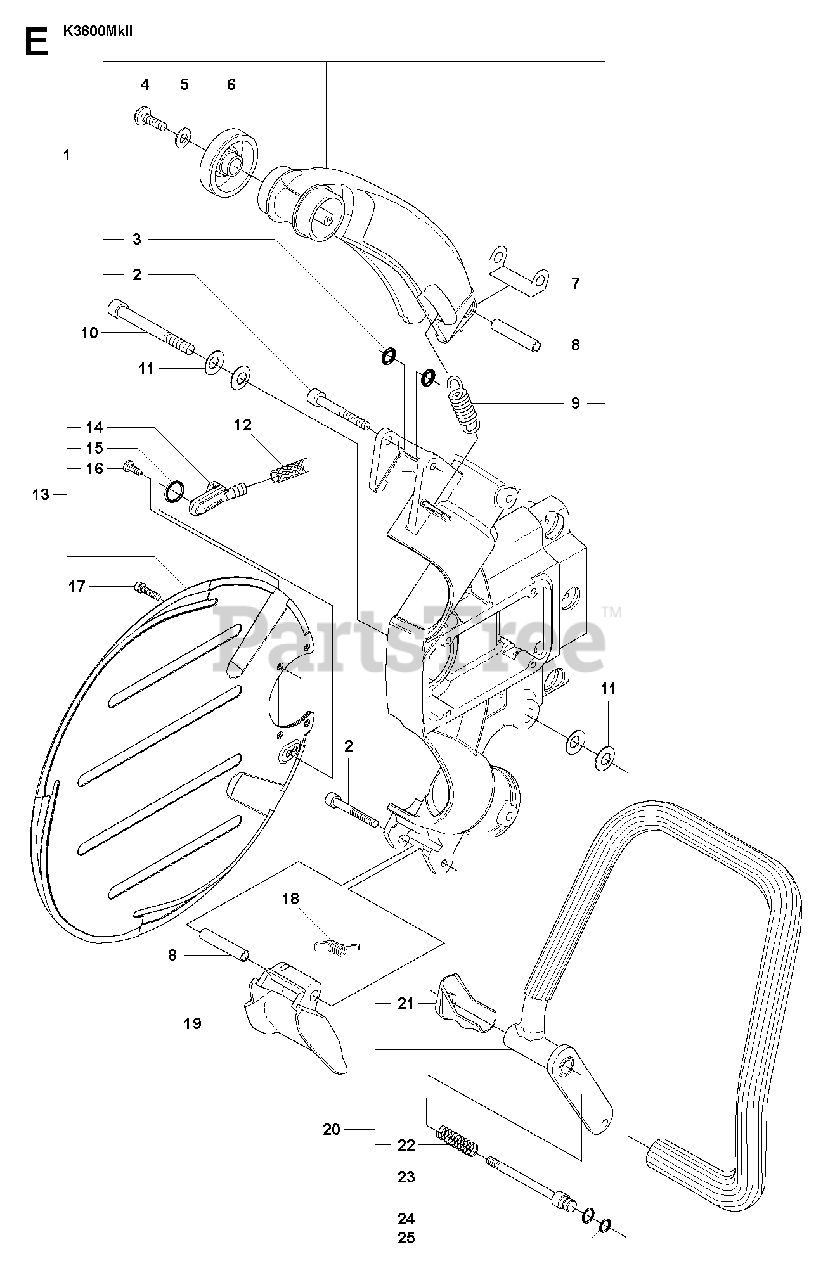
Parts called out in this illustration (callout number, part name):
1	BLADE GUARDIncl. 2 - 9
2	SCREW ITXSCM
8	SPACING TUBE
15	O-RING
16	SCREW CRPANT
17	SCREW ITXSCM
20	HANDLE ASSYIncl. 21 - 25
